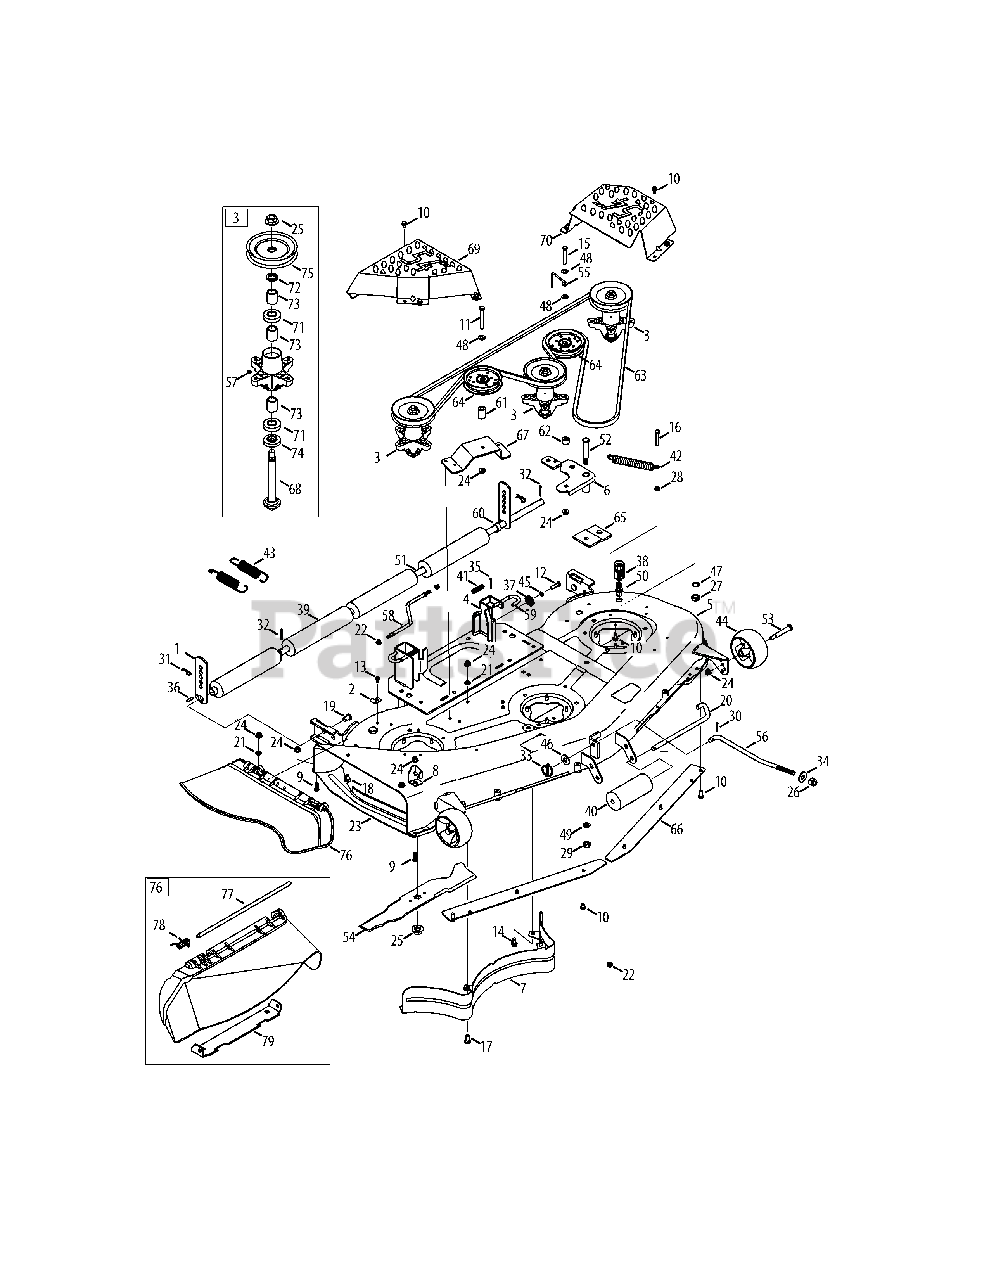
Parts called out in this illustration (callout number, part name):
2	Retainer Hook Bracket
3	Spindle Assembly
4	Deck Hanger Bracket Assembly
5	Deck Assembly
6	Idler Assembly
7	Inner Baffle
8	Deflector Chute Stop
9	Hex Screw, 3/8-16 x 1.00
10	Taptite Screw, 5/16-18 x .750
11	Hex Screw, 3/8-16 x 3.00
12	Hex Screw, 5/16-18 x 1.25
13	Hex Screw, 1/4-20 x .500
14	Taptite Screw, 3/8-16 x 0.750
15	Hex Screw, 3/8-16 x 2.50
16	Hex Screw, 5/16-18 x 2.00
17	Carriage Bolt, 3/8-16 x 1.00
18	Carriage Bolt, 3/8-16 x 0.75
19	Clevis Pin, .50 DIA x .78 LG
20	Roller Pin, 1/2 DIA x 7.31 LG
21	Push Nut, 3/8
22	Flangelock Nut, 5/16-18
23	Finger Guard
24	Flangelock Nut, 3/8-16
25	Flange Nut, 5/8-18
26	Flexlock Nut, 1/2-13
27	Hex Nut, M16-1.5 DIN 936
28	Hex Nut, 5/16-18
29	Hexlock Nut, Counterlock, 1/2-13
30	Cotter Pin, 3/32 x 1.0
31	Click Pin, .092 x 1.64 LG
32	Cotter Pin, 5/32 x 1.25
33	Lynch Pin, .1875
34	Washer, .630 x 1.25 x .180
35	Cotter Pin, 1/8 x 1.25
36	Spring Pin, 1/4 DIA x 1.00 LG
38	Water Nozzle Adaptor
39	Deck Roller
40	Front Roller
41	Compression Spring, .535 OD x 1.751 LG
42	Extension Spring, .85 OD x 5.915 LG
43	Extension Spring, 1.15 OD x 5.99 LG
44	Deck Wheel
45	Lock Washer, 5/16
46	Flat Washer, .531 x 1.25 x .100
47	Lock Washer, 5/8
48	Flat Washer, .406 x .875 x .059
49	Lock Washer, 1/2
50	Deck Water Nozzle
51	Shaft, .750 x .47.12
52	Shield Screw, .625 x 2.50:1/2-13
53	Shoulder Bolt, .496 x 2.50:3/8-16
55	Belt Keeper Rod
56	Deck Lift Rod
57	Lube Fitting
58	Deck Sway Rod
59	Deck Release Handle Rod
60	Spacer, .82 ID x 1.00 OD x .53
61	Spacer, .380 x .900 x 1.313
62	Spacer, .385 ID x .88 x .64
64	Idler Pulley, 4.25"DIA
65	Pulley Stabilizer Bracket
67	Stationary Idler Bracket
68	Spindle Shaft, 6.95 LG
69	RH Spindle Cover
70	LH Spindle Cover
71	Ball Bearing, .787 ID x 1.85 OD x .551
72	Spacer, .790 ID x 1.25 OD x .175
73	Spacer, .80 x 1.10 x 1.322 LG
74	Spacer, .79 x 1.82 x .55 LG
75	Deck Pulley
76	Chute Assembly
78	Torsion Spring, .44 ID x 2.0
79	Chute Bracket
